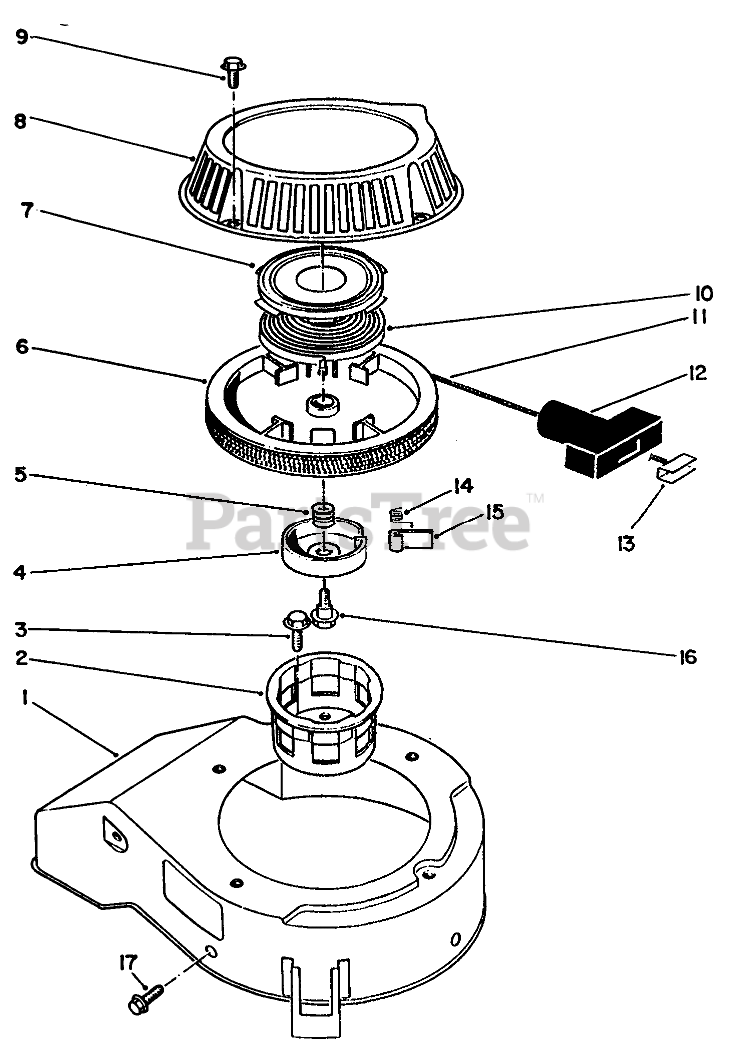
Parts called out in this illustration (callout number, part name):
1	COVER
2	CUP - STARTER
4	RETAINER
5	SPRING
7	Retainer-Recoil Spring
9	SCREW-HHF
10	Spring-Recoil
11	ROPE-STARTER
12	HANDLE-RECOIL
13	Insert Handle
14	SPRING
